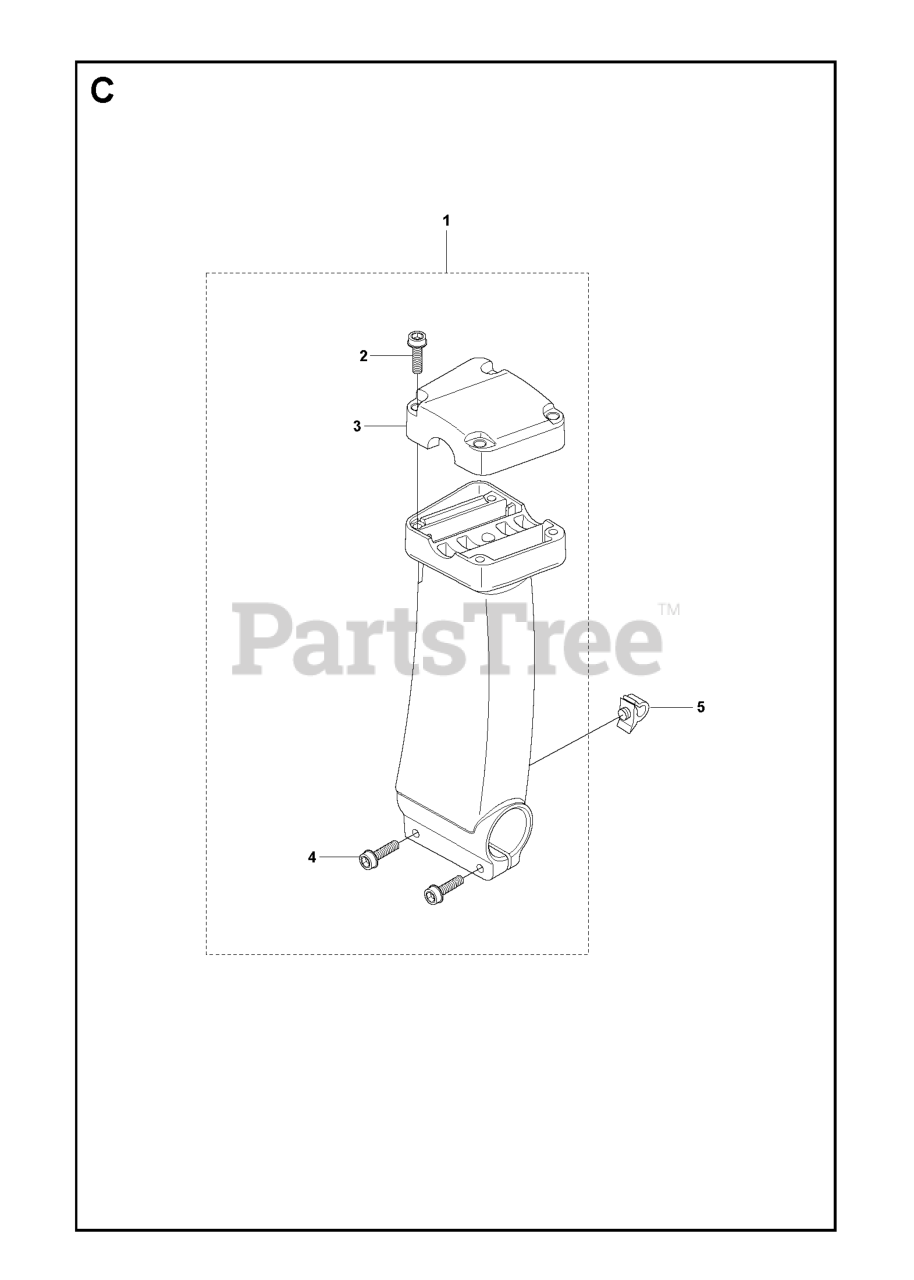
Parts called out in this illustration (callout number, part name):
1	HANDLEBAR BRACKET CPL
2	SCREW
3	HANDLEBAR BRACKET
4	SCREW IHSCM
